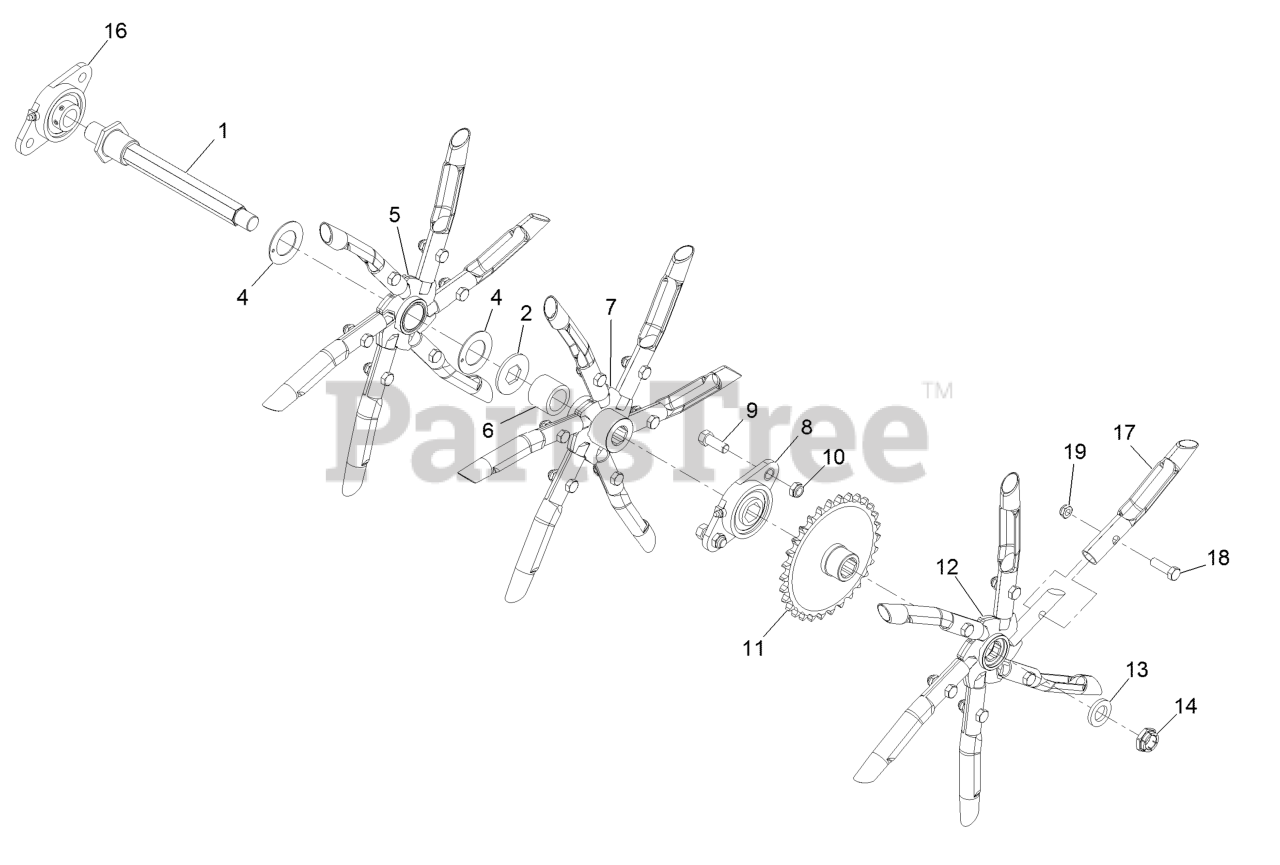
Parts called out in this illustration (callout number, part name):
1	Tine Shaft ASM
2	Keeper-Tine, Floating
4	Washer-Thrust
5	Floating Spyder ASM
6	Spacer-Tine
7	Driven Spyder ASM
8	Bearing-Hex Bore
9	Screw-HH
10	Nut-Lock
11	Sprocket ASM
12	Driven Spyder ASM
13	Washer-Spacer
14	Nut-Lock
16	Bearing-Round Bore
17	Tine-Coring (3/4 Inch)
18	Screw-HH 3/8-16 X 1 1/4
19	Nut-Nyloc 3/8-16 Thin
